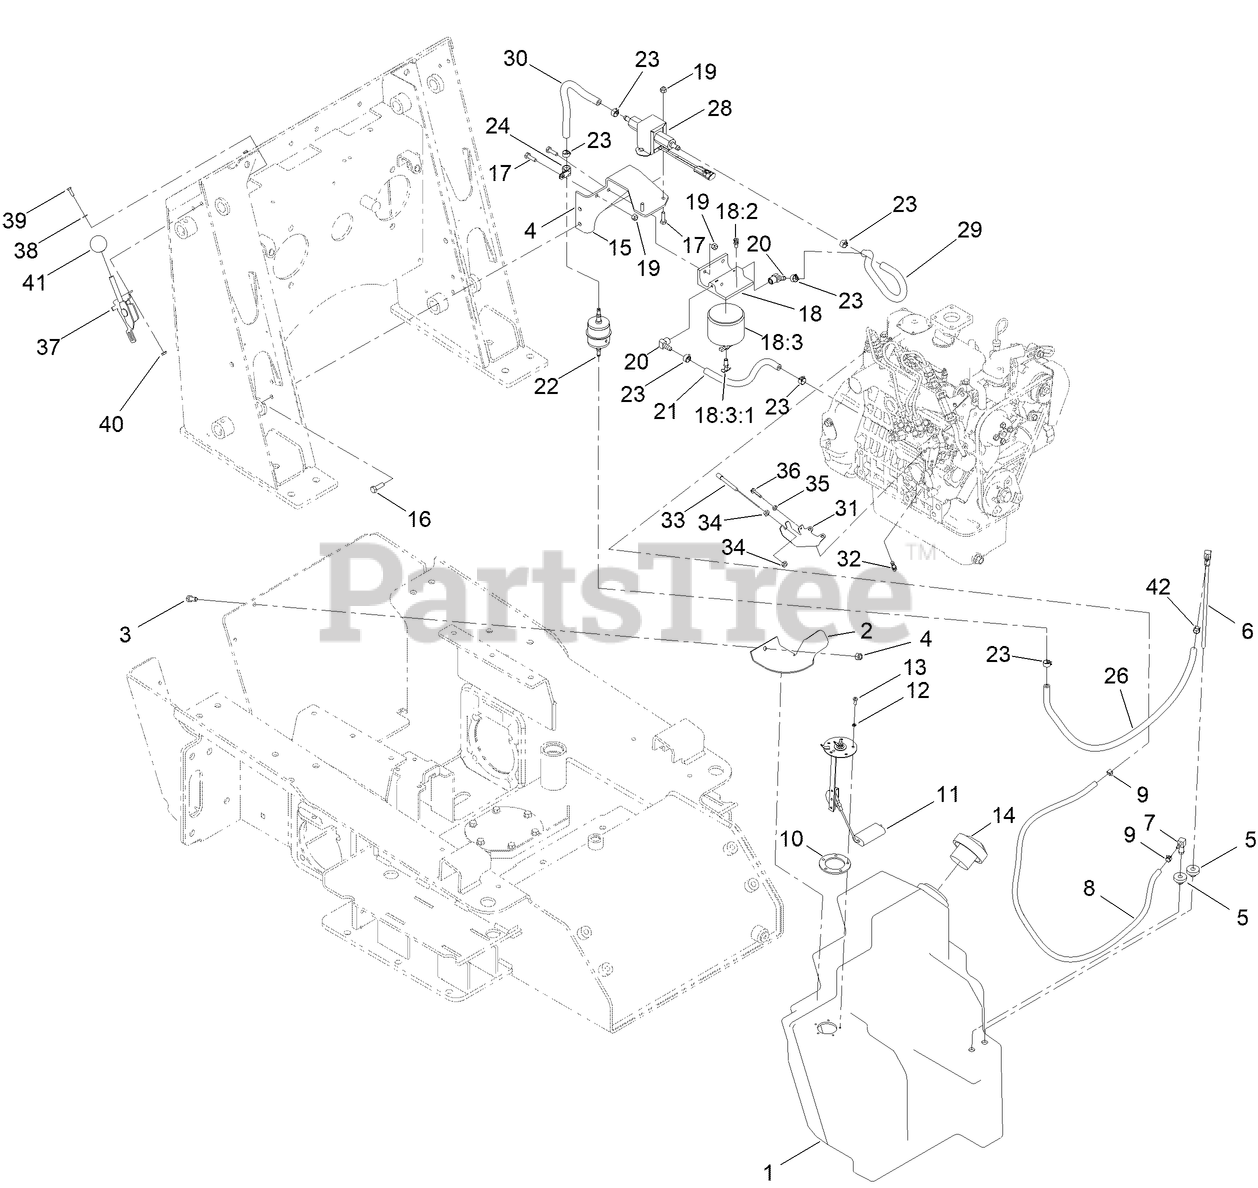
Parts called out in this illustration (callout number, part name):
1	TANK-FUEL
2	CLAMP-TANK, FUEL
3	SCREW-HH
4	NUT-LOCK, NI
5	BUSHING
6	PIPE-STAND
7	FITTING-ELBOW, 90 DEG
8	HOSE-FUEL
9	CLAMP-HOSE
10	GASKET-SENDER, FUEL
11	SENDER-FUEL
12	WASHER-LOCK
13	SCREW-PPH
14	CAP-DIESEL
15	BRACKET-PUMP,FUEL
16	SCREW-HH
17	SCREW-HH
18	FILTER HEAD ASM
18:2	VENT-AIR
18:3	ELEMENT-SPIN ON
18:3:1	VALVE-DRAIN
19	NUT-LOCK, NI
20	FITTING-HYD, 90
21	HOSE-FUEL
22	FILTER-FUEL
23	CLAMP-HOSE
24	CLAMP-R
26	HOSE-FUEL
28	PUMP-FUEL, ELECTRIC
29	HOSE-LP
30	HOSE-FUEL
31	BRACKET-SUPPORT, THROTTLE
32	SWIVEL-STOP, CABLE
33	CABLE-THROTTLE
34	NUT-JAM
35	NUT-HEX
36	SCREW-HWHTF
37	LEVER-CONTROL
38	WASHER-FLAT
40	NUT-KEPS
42	CLAMP-HOSE
